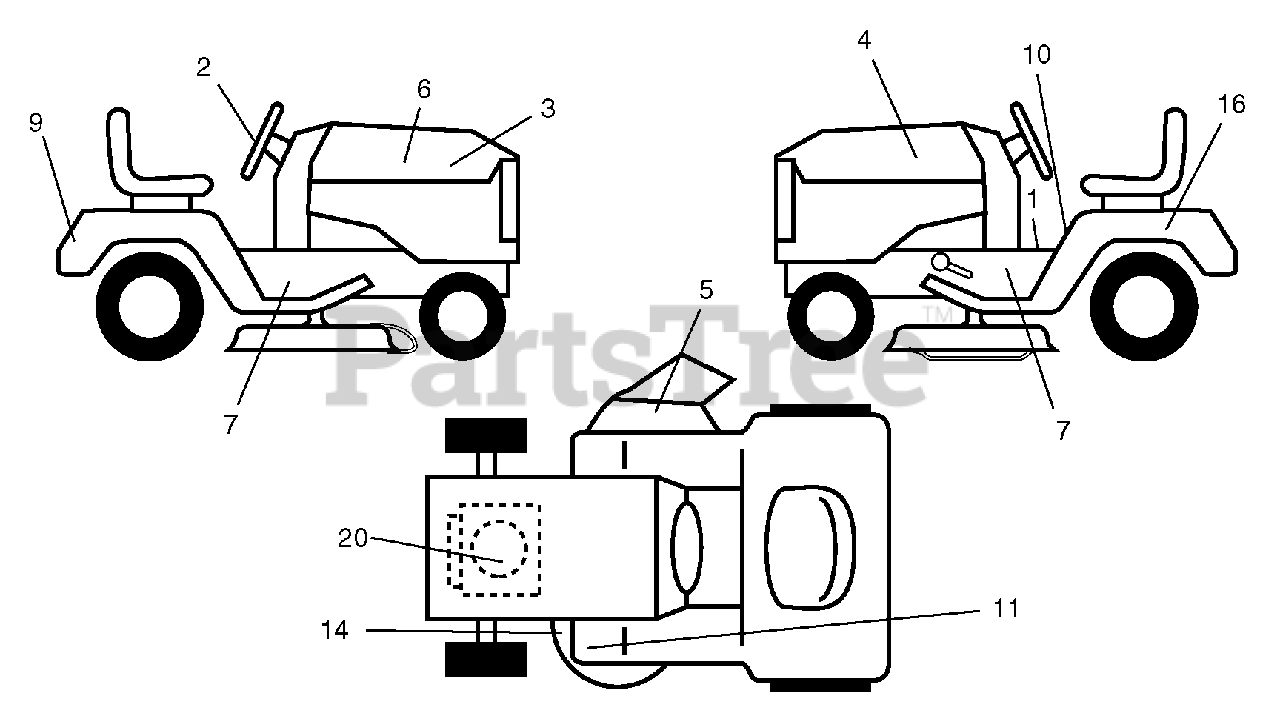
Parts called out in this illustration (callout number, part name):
1	Decal Instruction Operat English
2	Decal Steering
3	Decal Hood Rh
4	Decal Hood Lh
5	Decal Deck "B"
6	Decal Replace
7	Decal Chassis 6 Sp/42
9	Decal Fender Logo
10	Decal Danger English
11	Decal Clutch/brake
14	Decal V-belt Schematic 42"
16	Decal Battery Danger/Poison
20	Decal HP Engine
